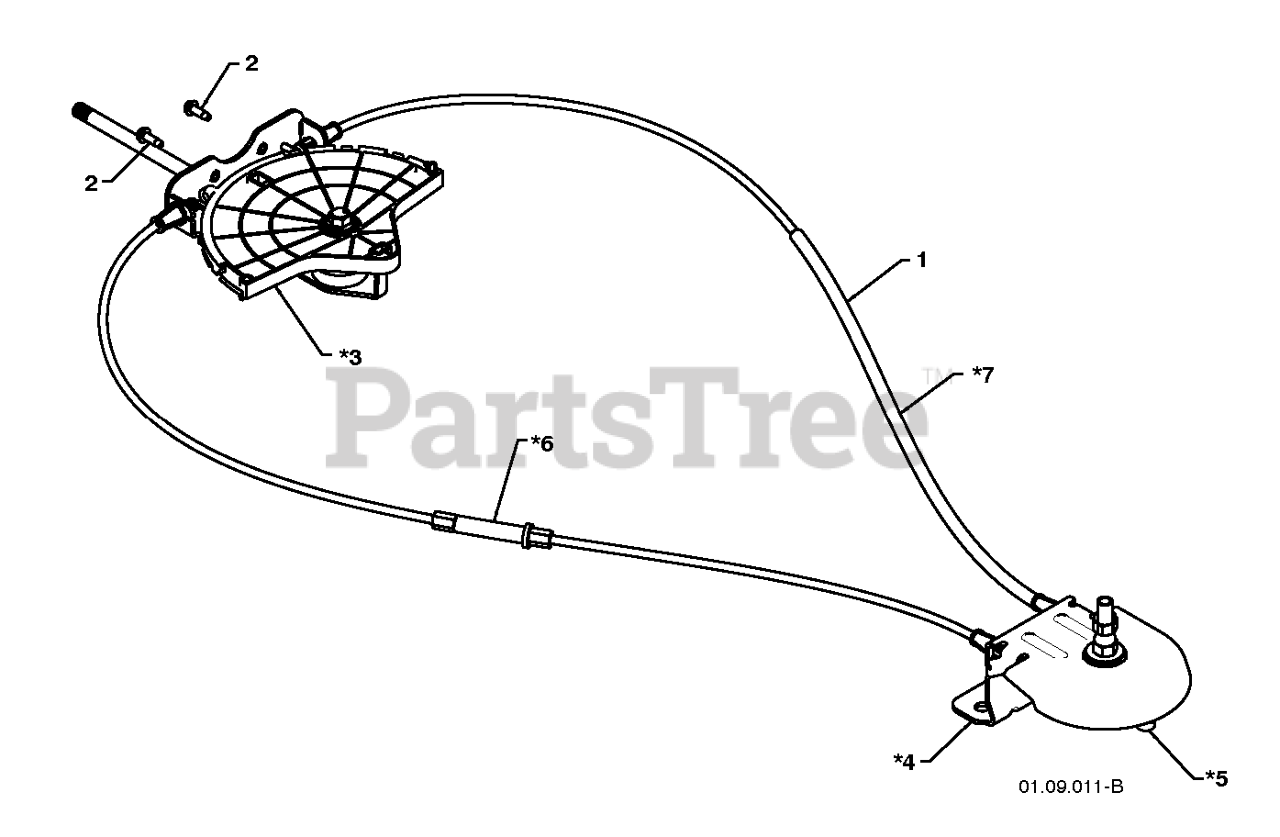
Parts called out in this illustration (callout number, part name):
1	RB LEVER.CABLE.ASM.ROTATR.PLTD
2	SCREW #10-24 X 5/8
3	CHUTE.ROT.HEAD.SERVICE
4	SNOW.PIVOT.BRKT.GRY.SERVICE
5	SNOW.PIVOT.PULLY
6	SNOW.CABLE.ASM.ADJUSTABLE.GRAY
7	SNOW.CABLE.ASM.SERVICE
